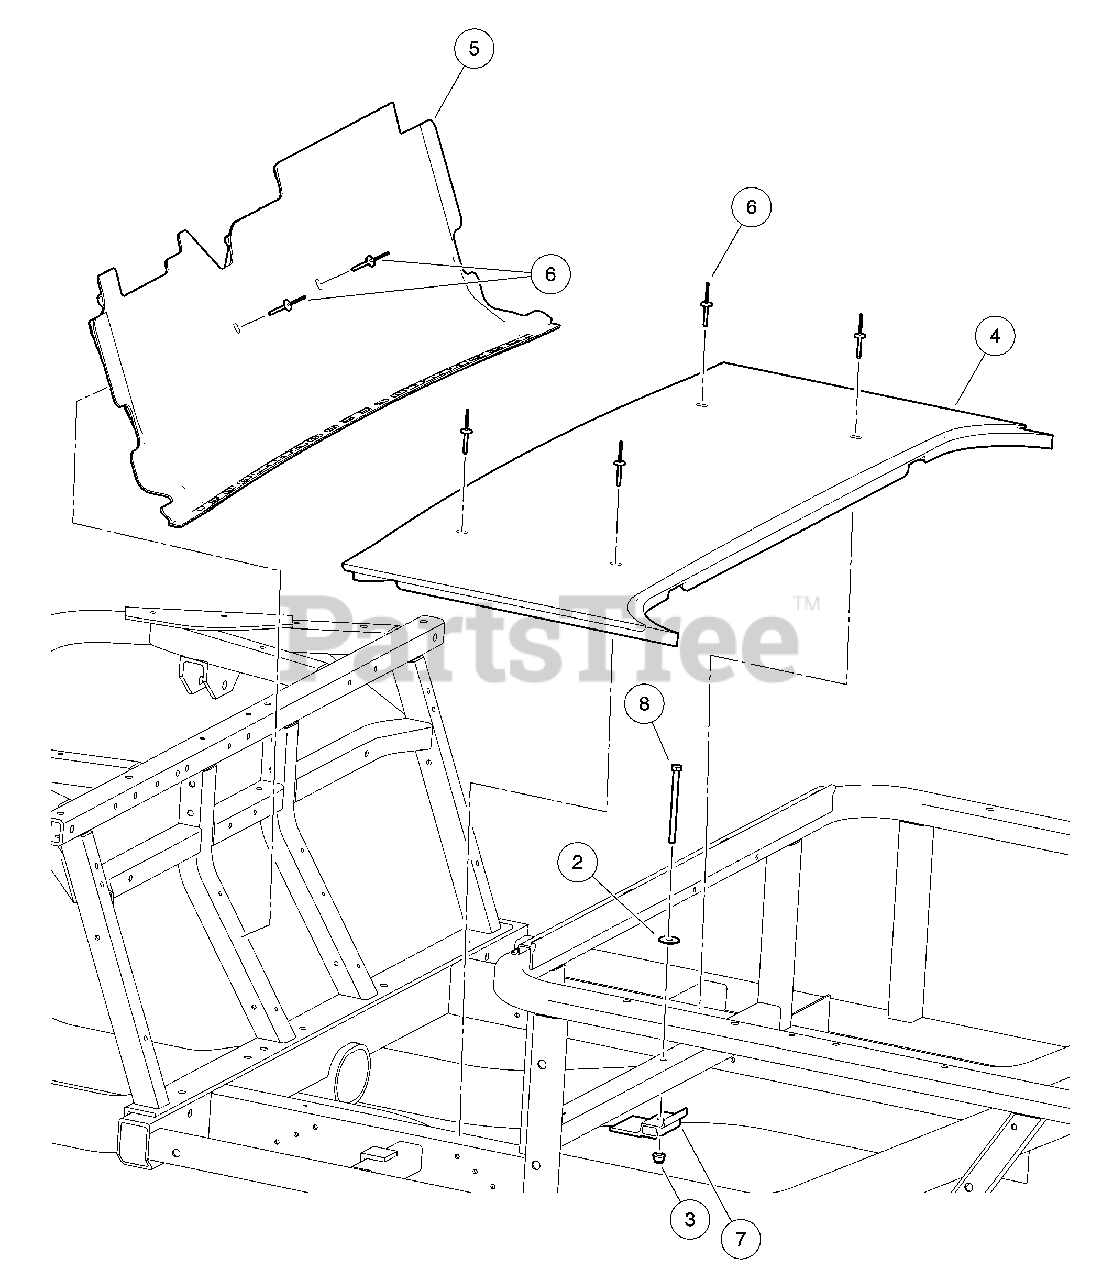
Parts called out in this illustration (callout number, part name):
1	Instl, Floorboard
2	Washer, 5/16 Type B Flat
3	Lock Nut, Flg M8 X 125 Nylon
4	Floorboard, Lower
5	Floorboard, Upper
6	3/16 X 119 Alum Rivet, Blk
7	Bracket, Support, Floorboard
8	Bolt, M8 X 125 X 110
